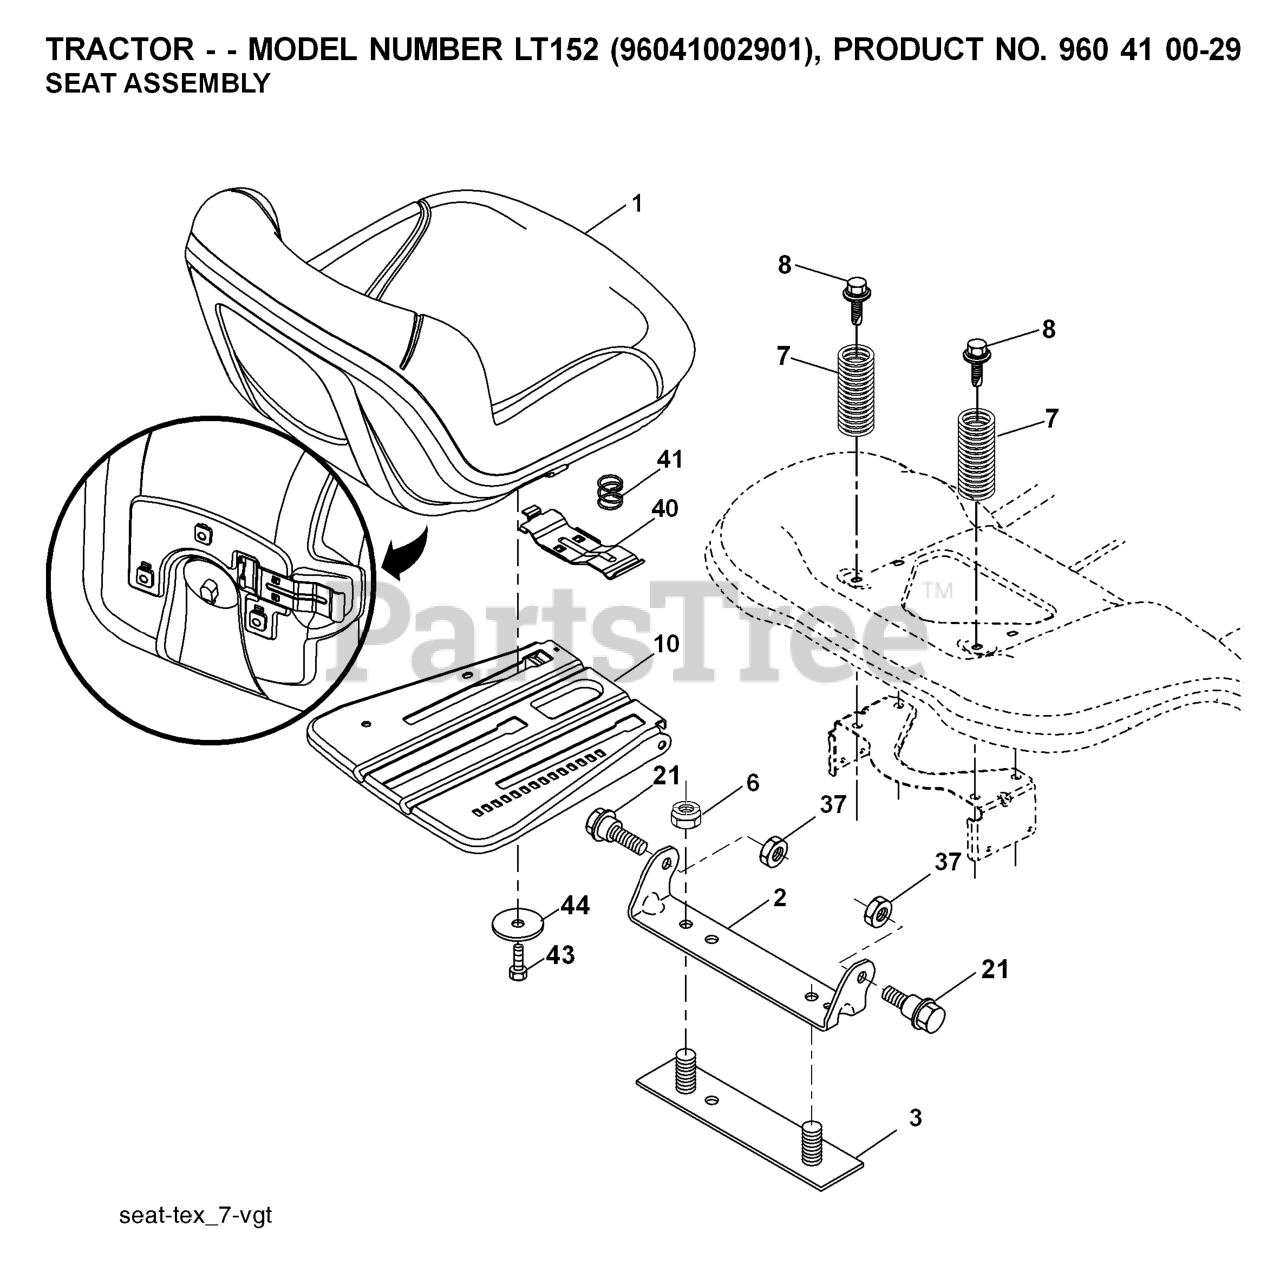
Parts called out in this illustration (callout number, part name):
1	SEAT.TH130.GRY.MILSCO.
2	BRKT.PIVOT.FENDER
3	STRAP
6	NUT
7	SPRING COMPRESSION
8	BOLT.5/16-18UNCX3/4 W/SEMS.BLK
10	PAN.ASM.SEAT.3PT
21	BOLT.SHOULDER.5/16-18
37	NUT.71038.31-18.HEX.NYLOCK
40	HANDLE.SLIDE.SEAT.TEX.BLACK
41	SPRING.LATCH.SEAT.TEX
42	WASHER.CUP.SEAT.
44	WASHER 13/32 X 2-3/8 X 12GA
